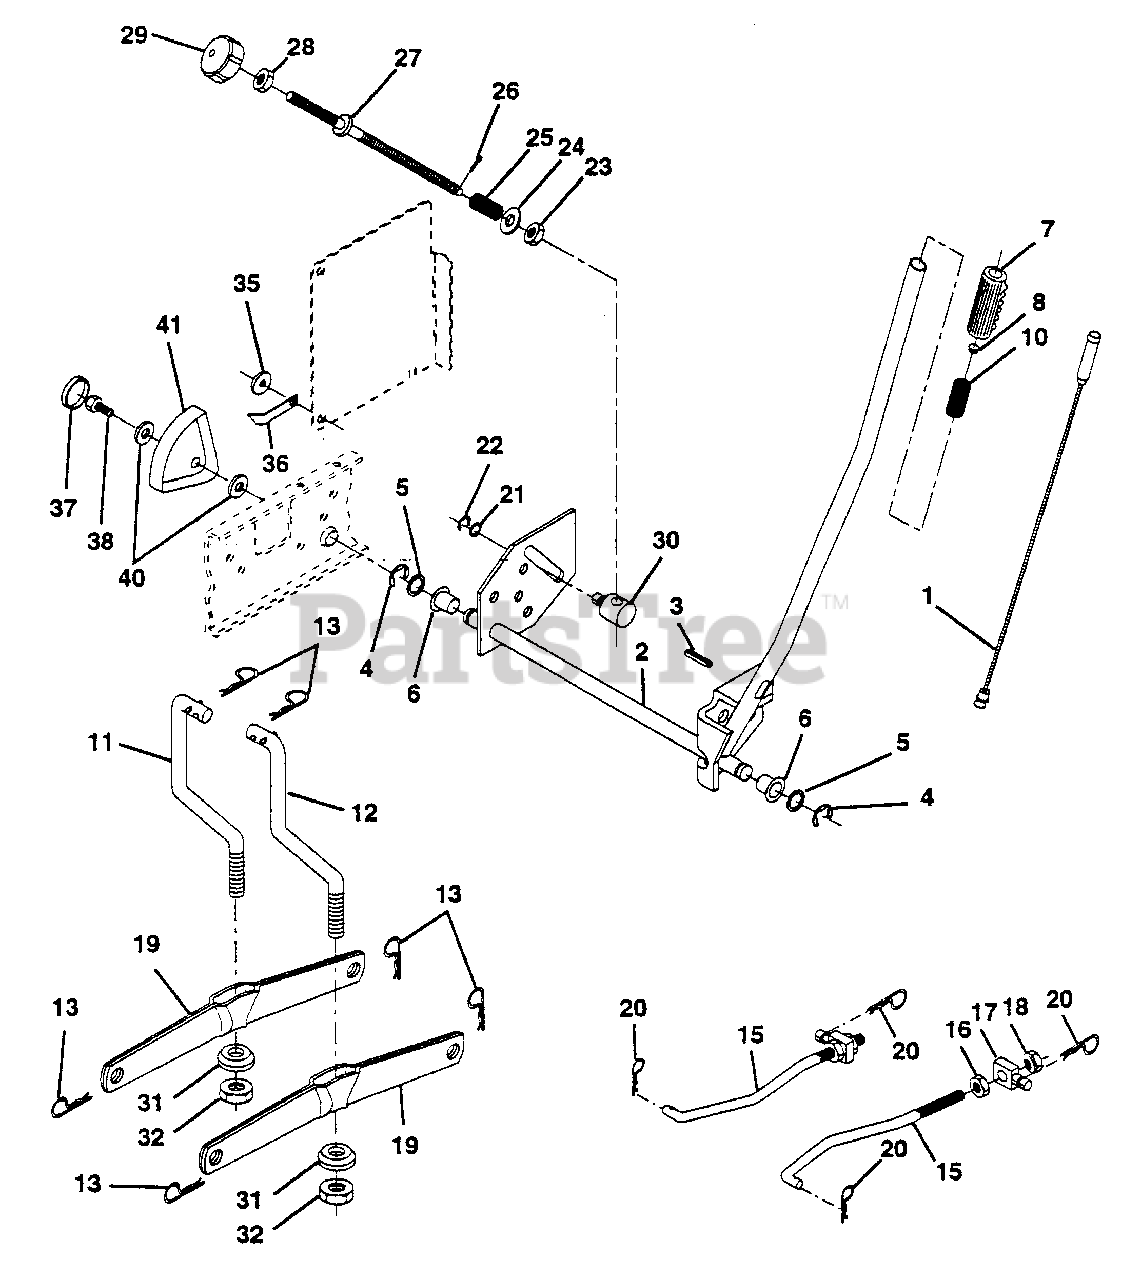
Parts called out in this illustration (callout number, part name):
1	Wire Asm Inner W/plunger 20 56
2	Shaft Asm Lift RH w/Inf
3	Pin Groove 1 500 Zinc
4	E Ring #5133-62
5	Washer 21/32 X 1 X 21 Ga
6	Bearing Nylon Blk 629 Id
7	Grip Handle Fluted Blk
8	Button Plunger Black
10	Spring Cprsn 3 750 Oiled
11	Link Lift LH
12	Link Lift RH
13	Retainer Spring
15	Link Front
16	Nut Jam Hex 1/2-13 Unc
17	Trunnion Blk Zinc
18	Nut Lock W/wsh 1/2-13unc
19	Arm Suspension Rear
20	Retainer Spring
21	Washer 15/32 X 314 X 16 Ga
22	Ring Klip #t5304-37
23	Nut Special
24	Washer 13/32 X 5/8 X 16 Ga
25	Spring Compression Inf. Hgt.
26	Pin Cotter 3/32 X 1/2
27	Rod Adj Lift Zinc 9 00 Wrk Lg
28	Nut Hex Jam 3/8-16 Unc
29	Knob Inf 3/8-16 Unc Blk W/sym
30	Trunnion Dp Stop Db I Thds PLT
31	Bearing Pvt Lift Spherical
32	Nut Crownlock 3/8-24
35	Washer Nylon .44 x .75 x .032
36	Pointer Height Indicator
37	Plug Hole Blk 1.485/1.515
38	Screw Thdrol 5/16-18 x 3/4 TYT
40	Washer 11/32 x 1-1/2 x 10 Ga.
41	Scale Ind. Height Blk
